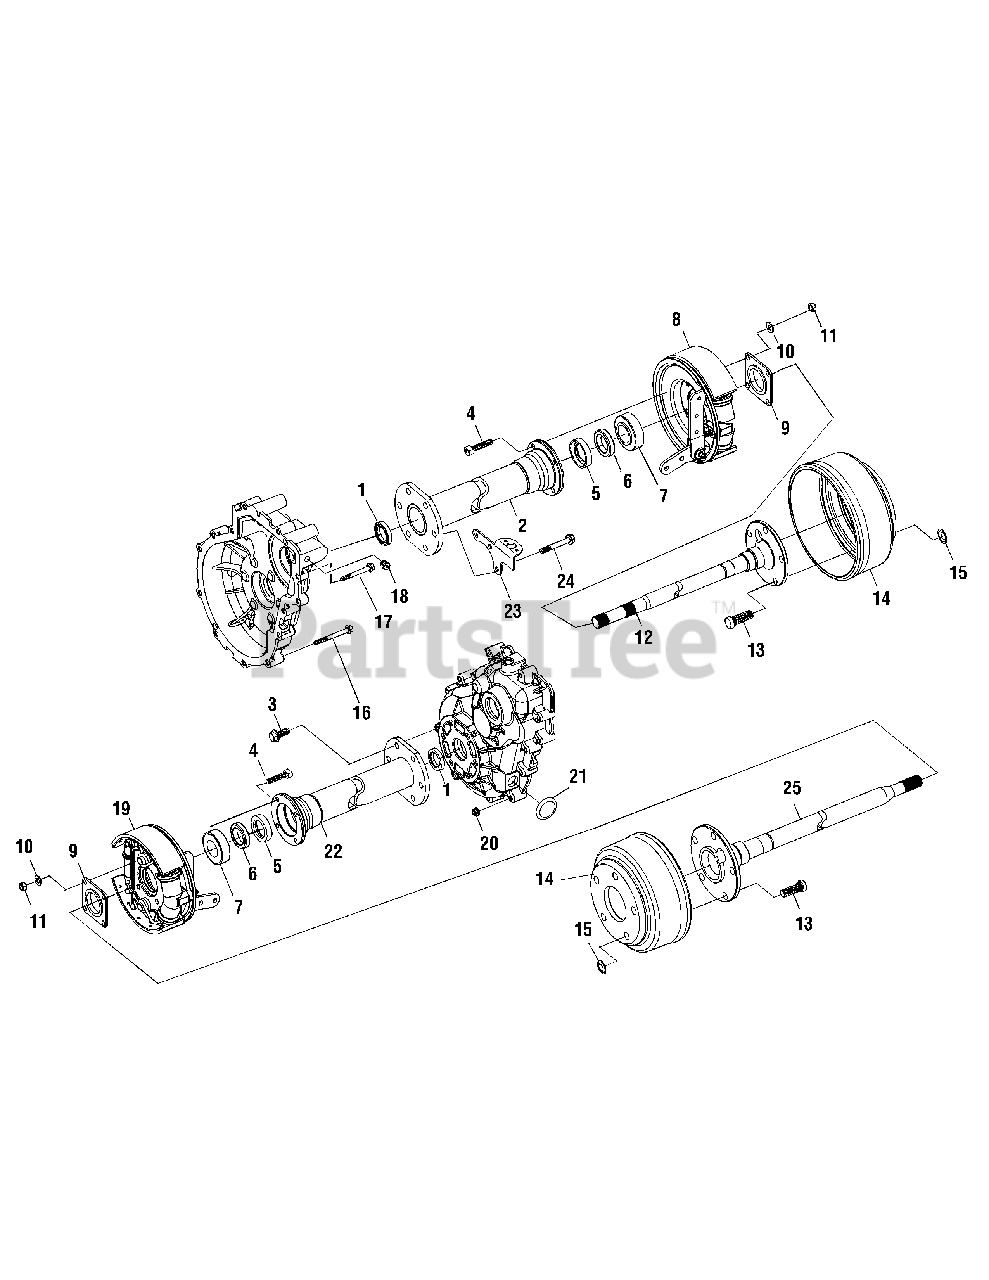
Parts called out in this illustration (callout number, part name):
2	Assembly, Tube
3	Screw, Flange Head
4	Screw, Socket Head
6	Ring, Retainer
7	Ass’y, Bearing, Tapered Roller
8	Assembly, Brake RH
9	Seal, Oil
10	Washer, Flat
14	Drum, Brake
15	Nut, Spring
16	Screw, Flange Head
17	Screw, Flange Head
19	Assembly, Brake LH
21	Plug, Rubber
22	Assembly, Tube
23	Bracket, Differential Lock Actuator
24	Screw, Flange Head
